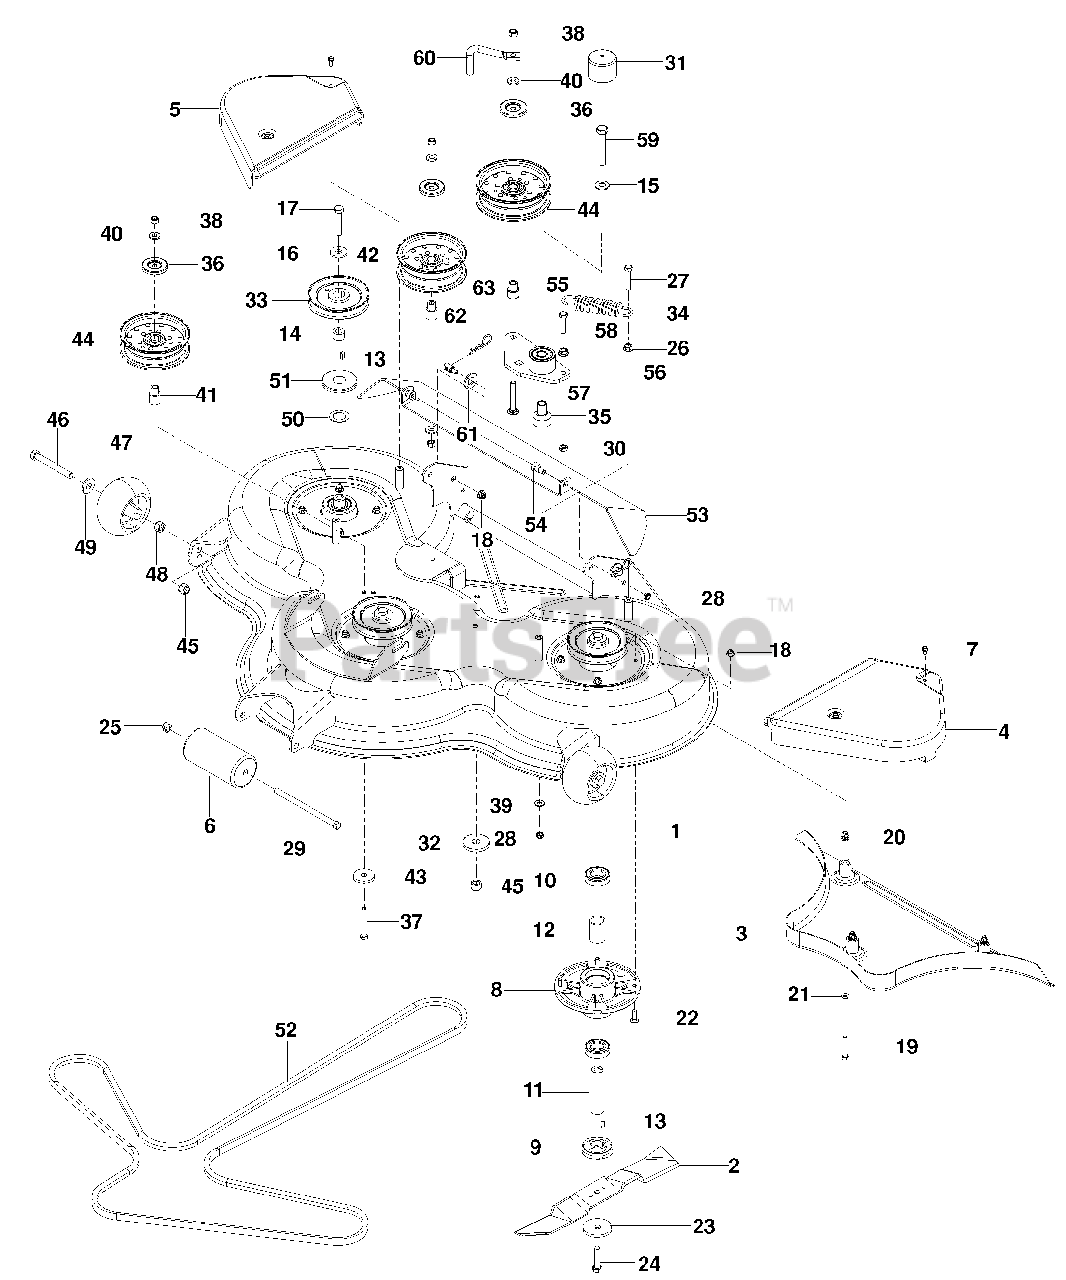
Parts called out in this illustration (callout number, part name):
1	DECK w/DECALS
2	BLADE
3	PLUG, MULCH
4	BELT SHIELD, LT
5	BELT SHIELD, RT
6	ROLLER
7	SCREW 1/4-20 x 5/8 SLF TAP
8	HOUSING, BEARING
9	BUSHING, BLADE
14	KEY RETAINER
15	WASHER 1/2 BELLEVILLE
17	HCS M12 x 1.75 x 60 GR 8.8
18	NUT 5/16-18 FLANGE NYLOC
19	HCS M8 x 1.25 x 50 GR 8.8
21	WASHER 5/16 SAE FLAT
22	RHSNB 5/16-18 x 1
24	HCS M12 x 1.75 x 50 GR 8.8
25	NUT 7/16-14 HEX CTRLK GR A
26	NUT 3/8-16 HEX WHIZLK
27	HCS 3/8-16 x 2
28	NUT 3/8-16 HEX JAM NYLOC
29	HCS 7/16-14 x 7
30	NUT 3/8-16 HEX JAM
31	CAP, VINYL
32	WASHER, SUPPORT
33	PULLEY, 48
35	PIVOT, BEARING
36	SHIELD, DUST
37	HCS 3/8-16 x 2 3/4
38	NUT 3/8-16 HEX NYLOC
39	WASHER 3/8 FLAT STD
40	WASHER 3/8 THICK
41	BUSHING, IDLER
42	PULLEY, IDLER (TALL)
43	WASHER, HEAVY
44	PULLEY, IDLER
45	NUT 1/2 HEX NYLOC
46	HCS 1/2-13 x 4
47	WHEEL, GAUGE
48	NUT 1/2-13 HEX JAM
49	WASHER 1/2 FLAT
51	DUST CAP, BOTTOM
53	GUARD, DISCHARGE
54	BOLT 3/8-16 x 3/8 SKT HD
55	BUSHING, IDLER
56	ARM, IDLER w/ BEARINGS
57	BOLT 3/8-16 x 2 3/4 CARRIAGE
58	HCS 3/8-16 x 1 1/2 GR 8
59	HCS 1/2-13 x 3
60	BELT KEEPER
61	WASHER 5/8 FLAT SAE
62	STUD w/ ANTI-ROTATE
